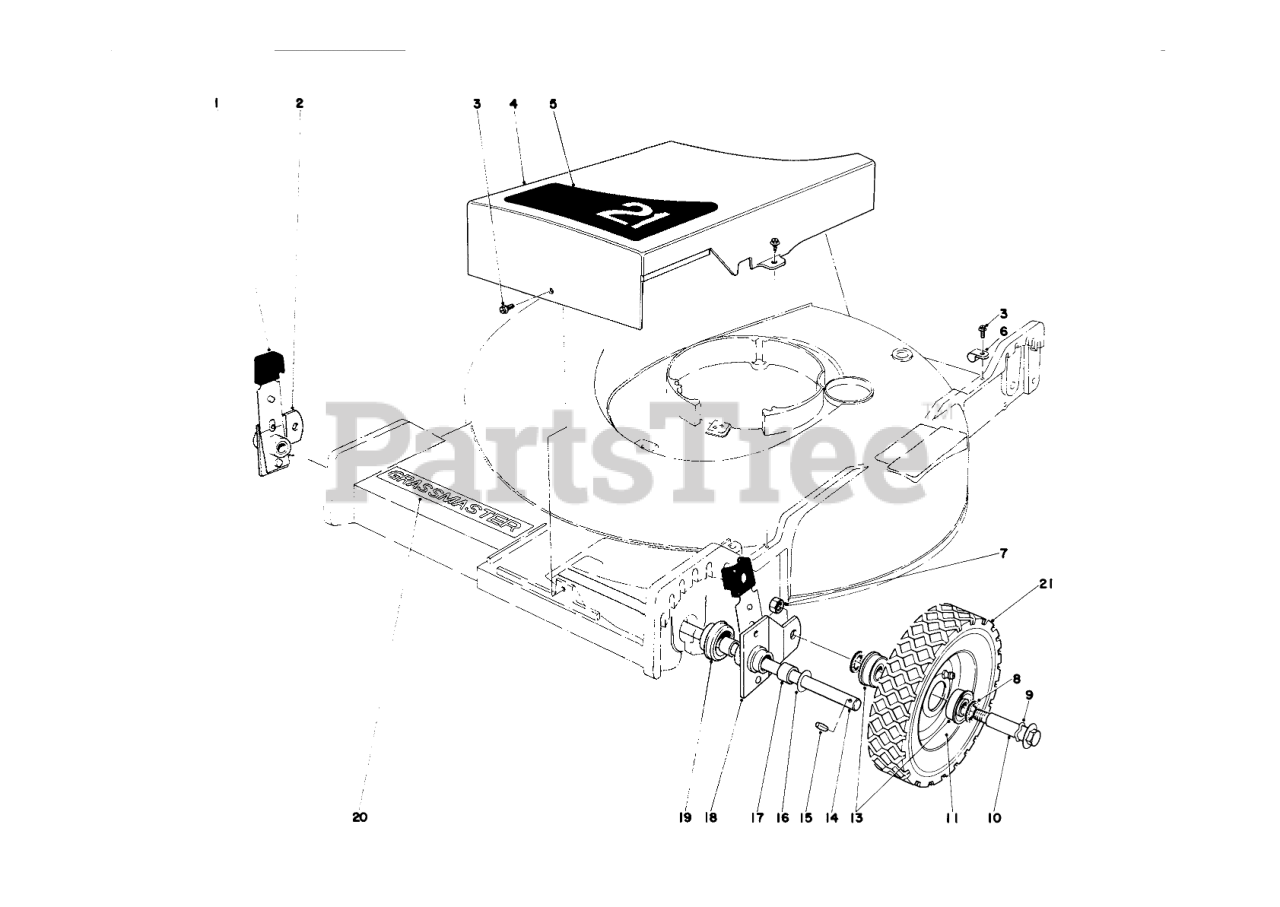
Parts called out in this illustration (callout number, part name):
1	KNOB-ARM
2	Pivot Arm (Incl. Ref. #17)
3	SCREW
4	Belt Cover
5	Decal
6	CABLE CLAMP
7	Nut
8	FELT WASHER
9	SPRING WASHER
11	Wheel & Tire assembly (Incl. Ref. #13 & 21)
13	BEARING-BALL
14	Shaft-Pivot Arm
15	PIN-GROOVED
16	WASHER-THRUST
17	BUSHING
18	Pivot Arm (Incl. Ref. #17)
19	End Cap
20	Decal Grassmaster
